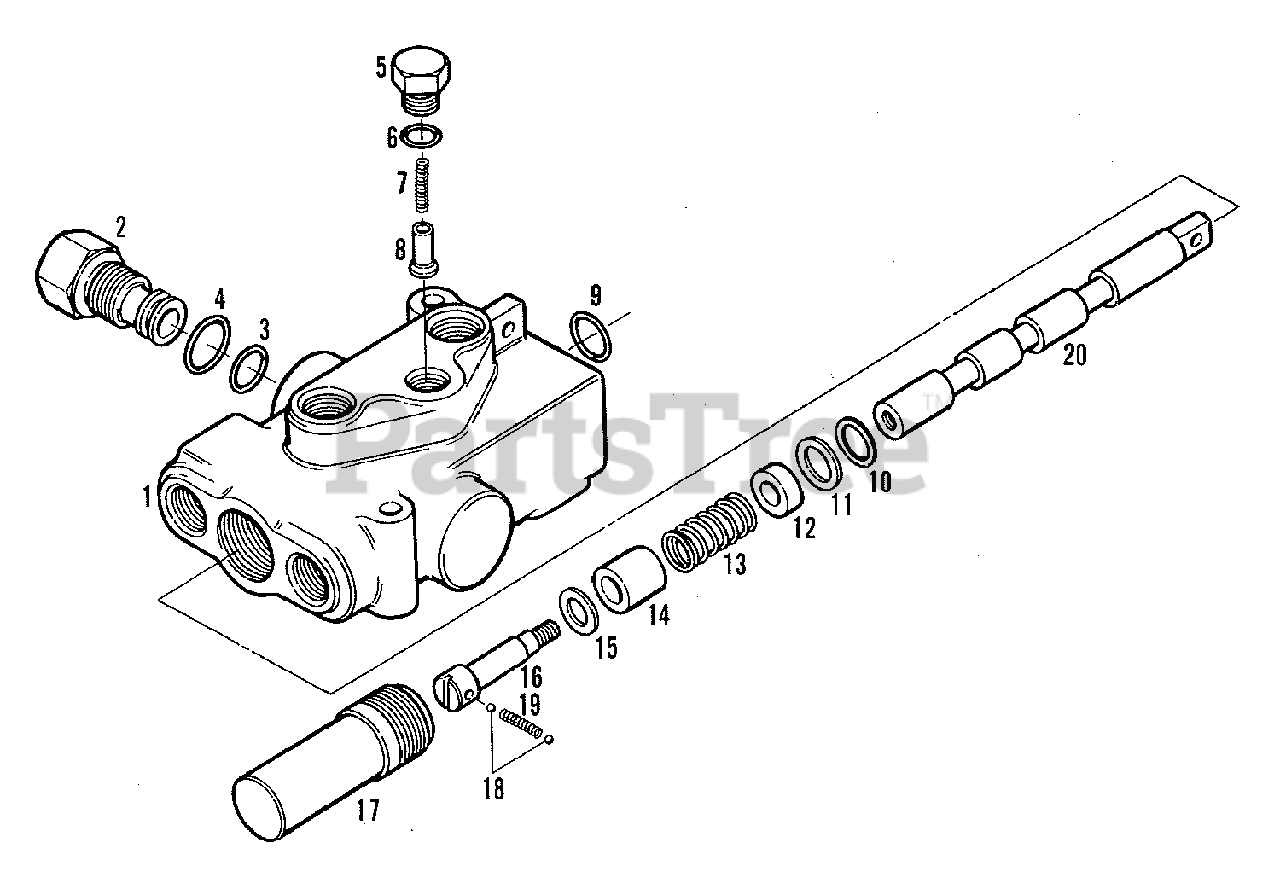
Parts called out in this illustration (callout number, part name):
1	BODY
5	PLUG, Check
14	STOP, Spool
16	STEM, Spool
20	SPOOL
